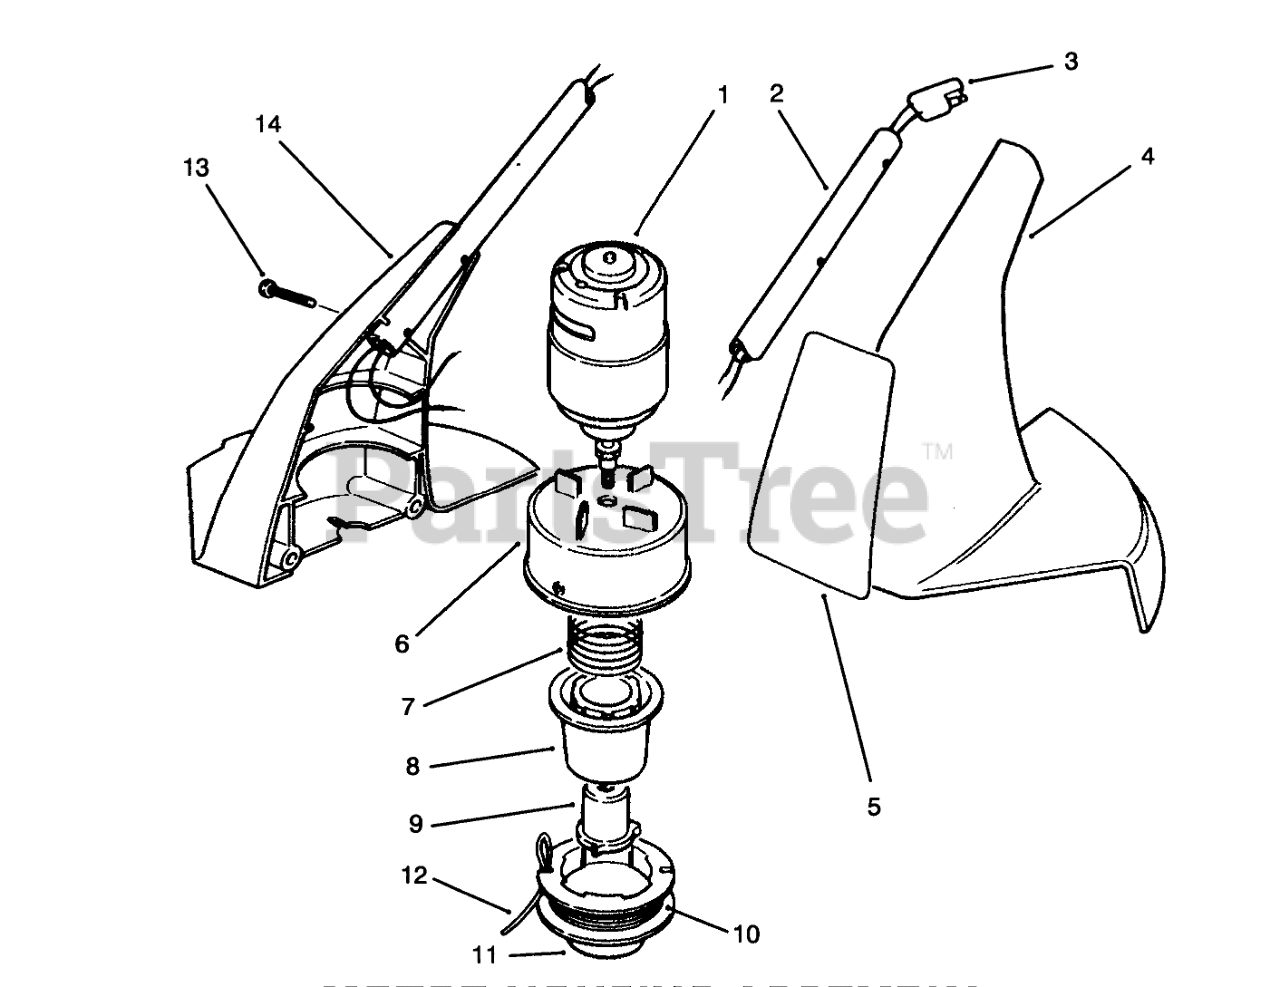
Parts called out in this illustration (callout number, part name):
1	MOTOR ASM
2	HANDLE-EXTENSION
3	WIRING HARNESS-LOWER
4	HOUSING, LH - 7"TRIMMER
5	DECAL - 7" TRIMMER
6	DRUM ASM-4 BLADE
7	SPRING-COMPRESSION
8	CORE - SPOOL
9	DRIVER
10	Prewound Spool
11	CAP-SPOOL
12	Line-Cutting (30- .05 Dia.)
13	SCREW-PLASTITE
14	HOUSING, RH - 7"TRIMMER
